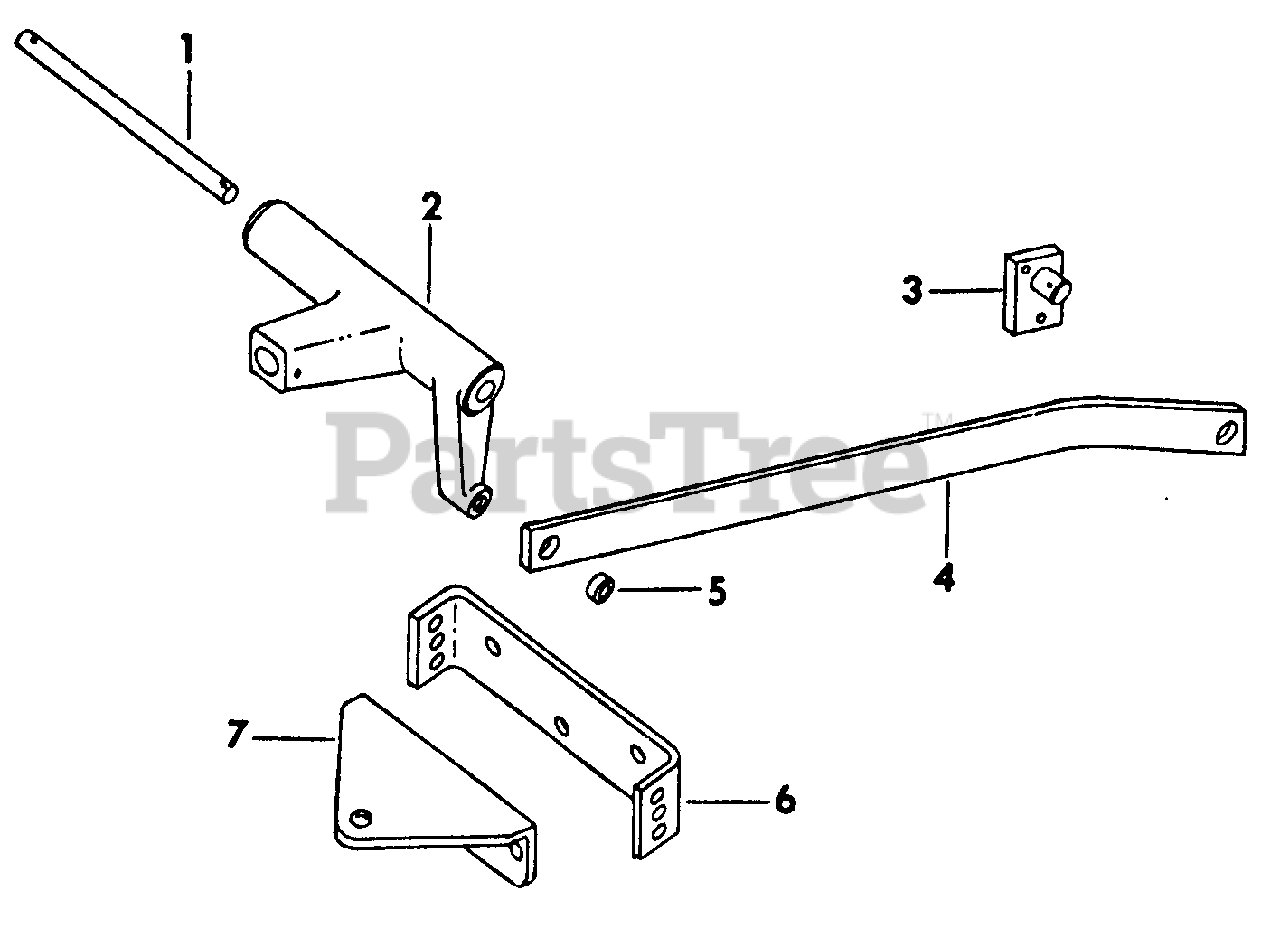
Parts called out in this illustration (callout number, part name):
1	Shaft, Lift Lever
2	Lever, Lift
3	Plate Assy, Lift Bar
5	Spacer, Lift Bar
7	Drawbar, Fixed
